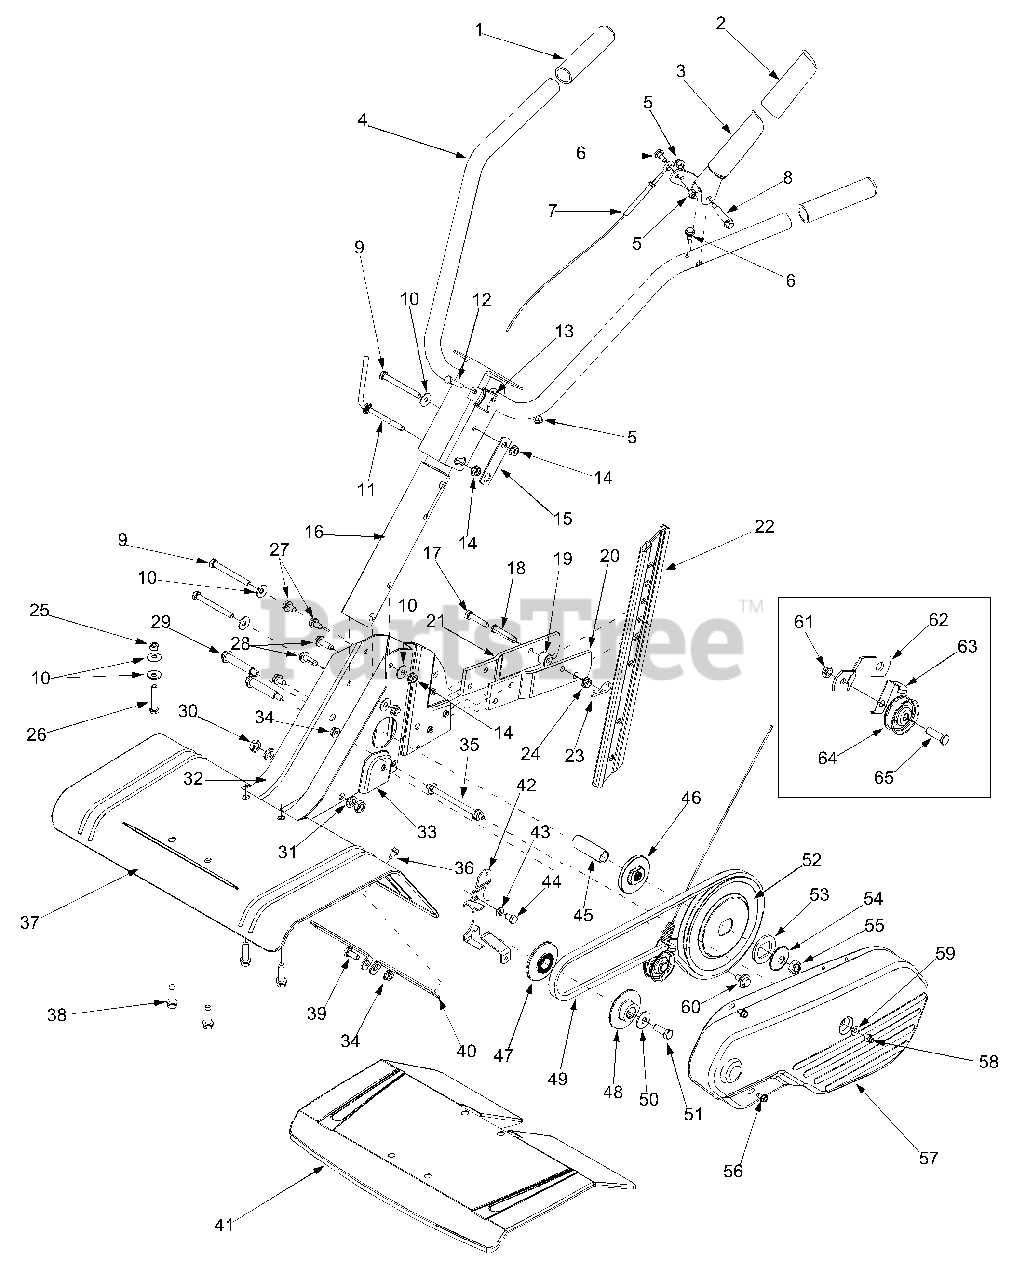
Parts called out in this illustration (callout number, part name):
2	Clutch Grip
5	Lock Nut Cap 1/4-20
6	Shoulder Screw
7	Clutch Cable
8	Shoulder Screw
9	Hex Cap Screw 5/16-18 x 3.0
10	Bell Washer .340 ID x .872 OD
11	Adjustable Handle Crank
12	Hex Cap Screw 1/4-20 x 1.5
13	Rope Guide
14	Flange Nut 5/16-18
15	Retainer Bracket
18	Clevis Pin 3/8 x 1.62
19	Spacer
23	Cotter Pin
24	Hex Flange Locknut 5/16-18
25	Hex Nut 5/16-18
26	Hex Cap Screw 5/16-18 x 1.75
27	Hex Washer Screw 5/16-18 x .625
28	Hex Washer Screw 5/16-18 x 1.0
29	Shoulder Screw
30	Jam Nut 7/16-20
31	Lock Washer 7/16
34	Flange Lock Nut 5/16-18
35	Belt Cover Belt
36	Hex Washer Screw 1/4-20 x .500
39	Hex Cap Screw 5/16-18
43	Lock Washer 5/16
44	Hex Cap Screw 5/16-24 x .50
45	Input Spacer .64 ID x 2.4 Lg
46	Pulley Adapter
47	Engine Inner Half Pulley
48	Engine Outer Half Pulley
49	Belt
50	Bell Washer .396 ID x 1.140 OD
51	Hex Cap Screw 3/8-24 x 1.0
52	Flat Pulley
53	Retainer Bearing Washer
54	Spherical Washer .531 ID x .620 OD
55	Jam Nut 1/2-20
56	Hex Washer Screw 1/4-20 x .50
58	Lock Nut Cap 1/4-28
59	Flat Washer .271 ID x .630 OD
60	Shoulder Screw
61	Jam Nut 3/8-16
63	Idler Keeper Bracket
64	Flat Idler
65	Hex Cap Screw 3/8-16 x 1.25
